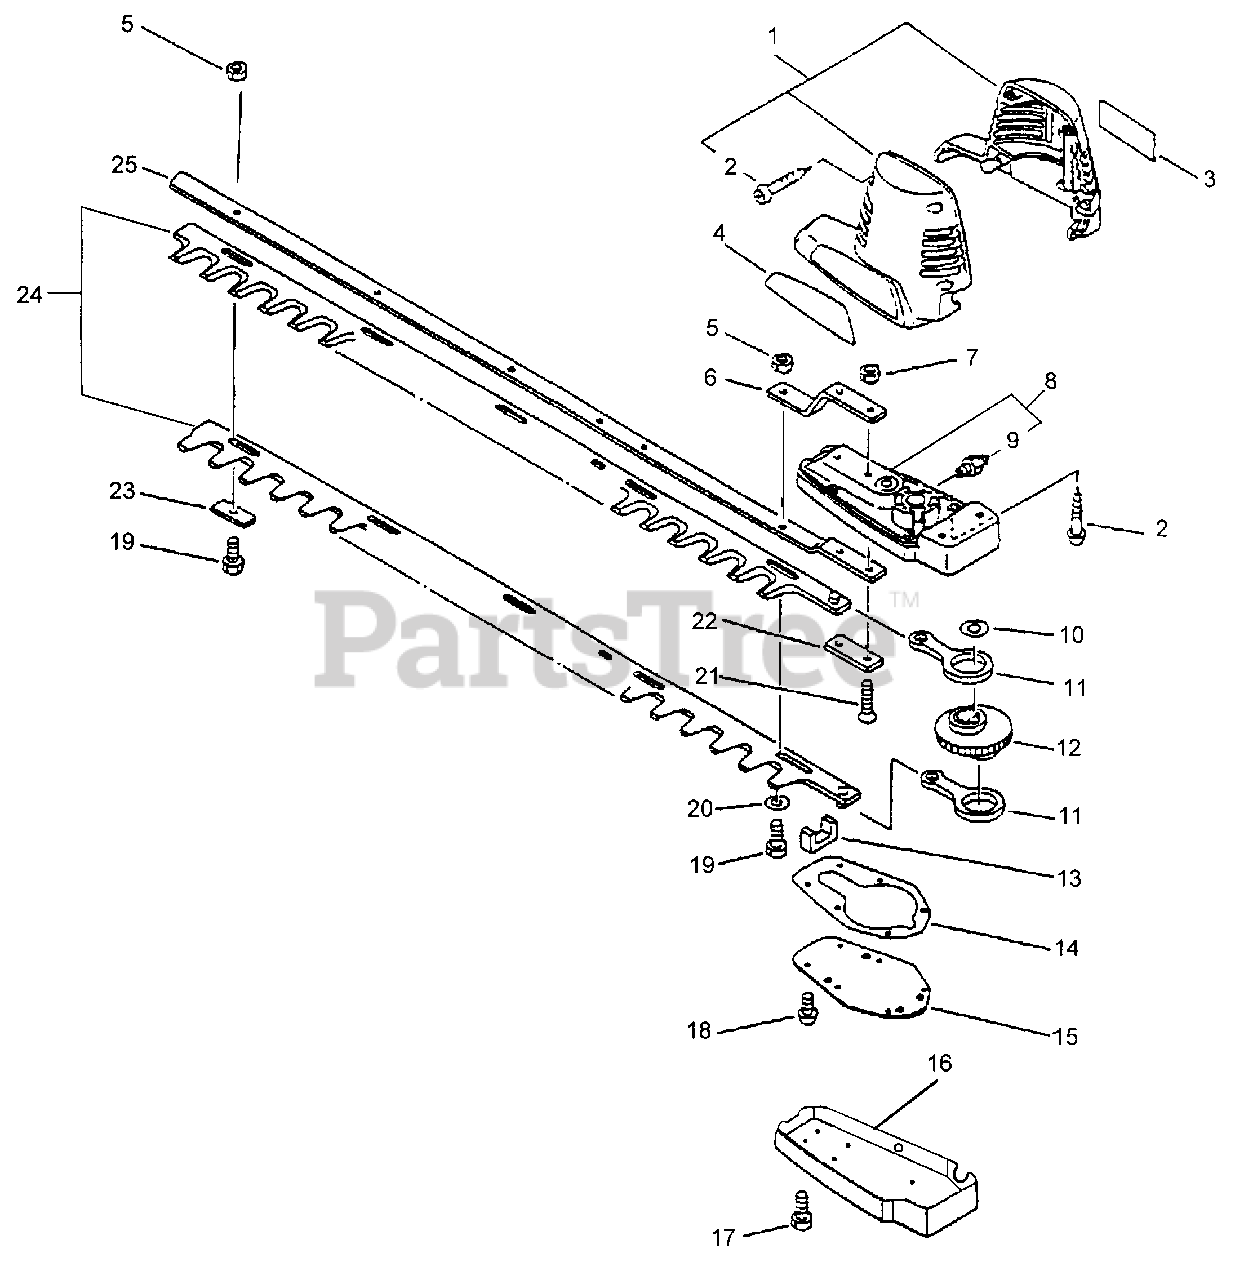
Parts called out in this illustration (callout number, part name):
1	MOTOR CASE KIT
2	SCREW 4×22
3	LABEL - CAUTION
4	LABEL - MODEL
6	PLATE, ANGLE
7	NUT, HEX M6
8	CASE, GEAR
9	FITTING, GREASE
11	ROD, CONNECTING
14	GASKET, GEAR CASE
15	LID, GEAR CASE
16	LID, GEAR CASE
17	SCREW 4×16
18	SCREW 4×12
19	BOLT 6×18
20	WASHER 6.5×15.5×0.6
21	SCREW 6×25
22	PLATE, EYE
23	INSULATOR
24	TRIMMER BLADE SET
25	SUPPORT, CUTTER
